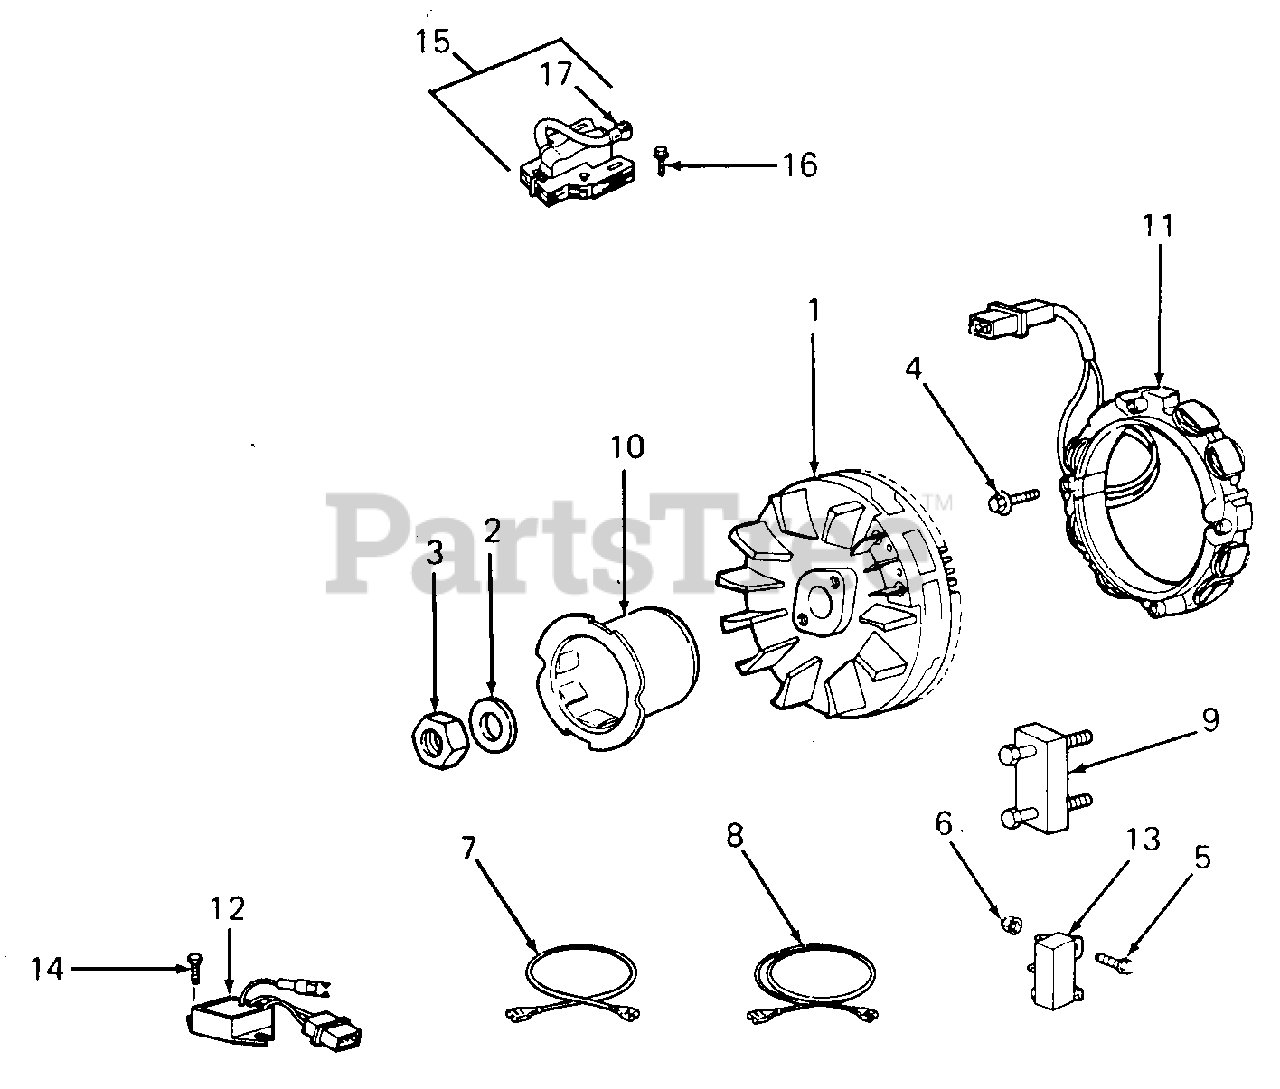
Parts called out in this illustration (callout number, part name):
1	Flywheel & Ring Gear
2	Washer, Spring
4	Screw, Mounting
5	Screw, Hex Hd
6	Nut, Nylock
7	Wire, Ground (Cyl #1)
8	Wire, Ground (Cyl #2)
9	Puller, Flywheel
10	Hub, Starter
11	Stator, 16 Amp
12	Regulator
13	Terminal, Ground
14	Screw, Mounting
15	Armature
16	Screw, Mounting
17	Terminal
